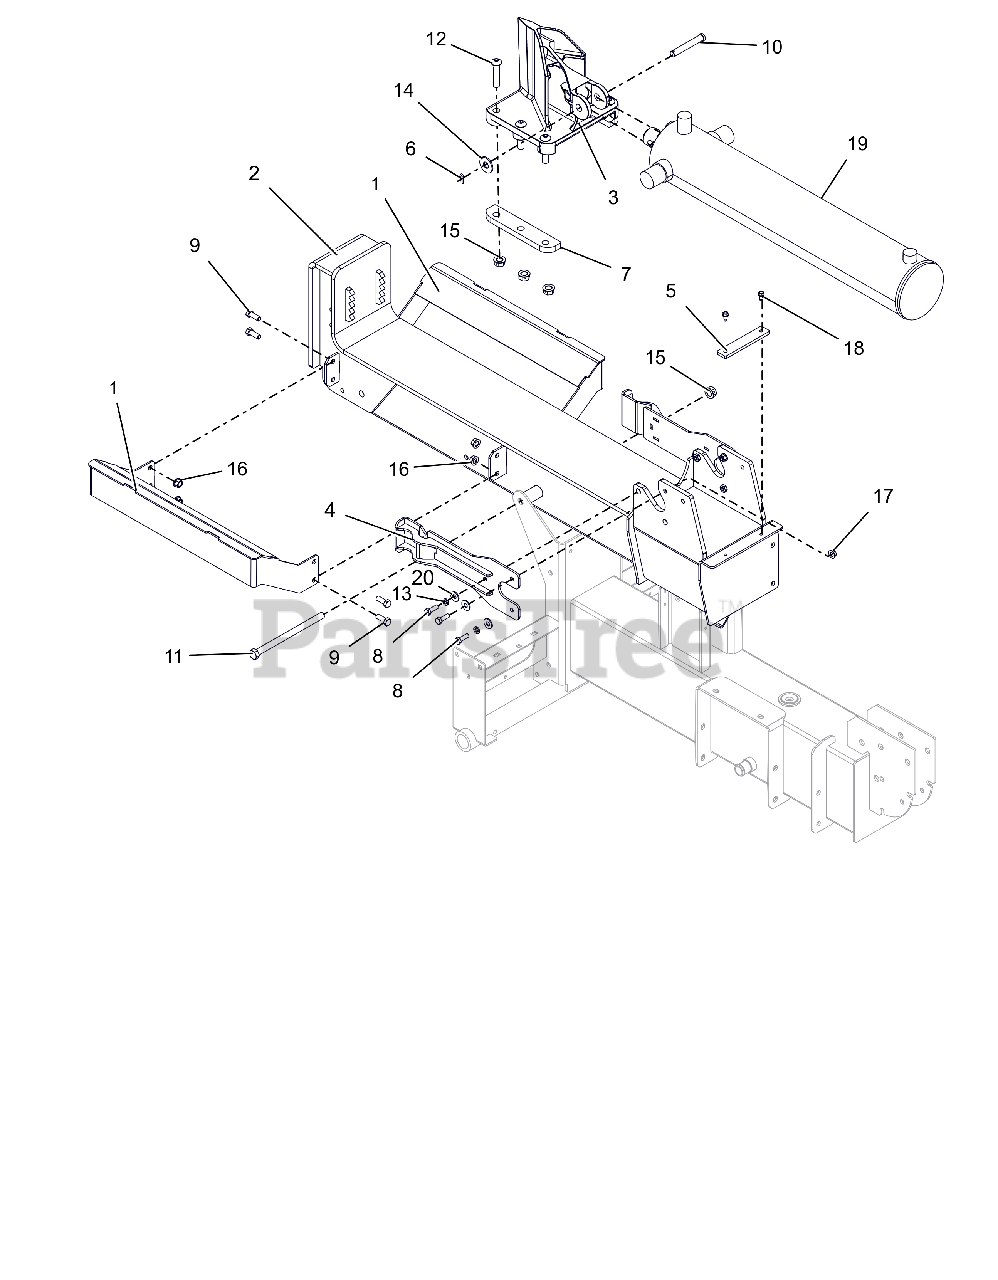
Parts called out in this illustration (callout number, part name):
1	WLDMT, CRADLE, LOG SPLITTER
2	WLDMT, BEAM - 27/34T SPLITTER
3	WEDGE-LOG SPLITTER-MACHINED
4	WLDMT, PLATE - STRIPPER
5	SPACER, CYLINDER
6	CLIP, SPRING
7	RETAINER-WEDGE
8	@BLT-HEX .31-18X1.00 GR5 YWZC
9	@BLT-HEX .38-16X1.00 GR5 YWZC
10	PIN-CLEVIS .500 X 3.250
11	@BLT-HEX .50-13X7.50 GR5 YWZC
12	SCR-SKH .500-13X2.250 BTH YZ
13	WSHR-LK .312X.097 HVY YWZC
14	@WSHR-FL-STL.563X1.38X.109YWZC
15	NUT-LK-CTR-FLG .50-13 YWZC
16	@NUT-LK-TOP-FLG .38-16 YWZC
17	@NUT-LK-TOP-FLG .31-18 YWZC
18	SCR-TAP .25-20X.50 HWH TR YWZ
19	CYLINDER,4.5 W/DECALS
20	@WSHR-FL-STL.38X.875X.083 YWZC
